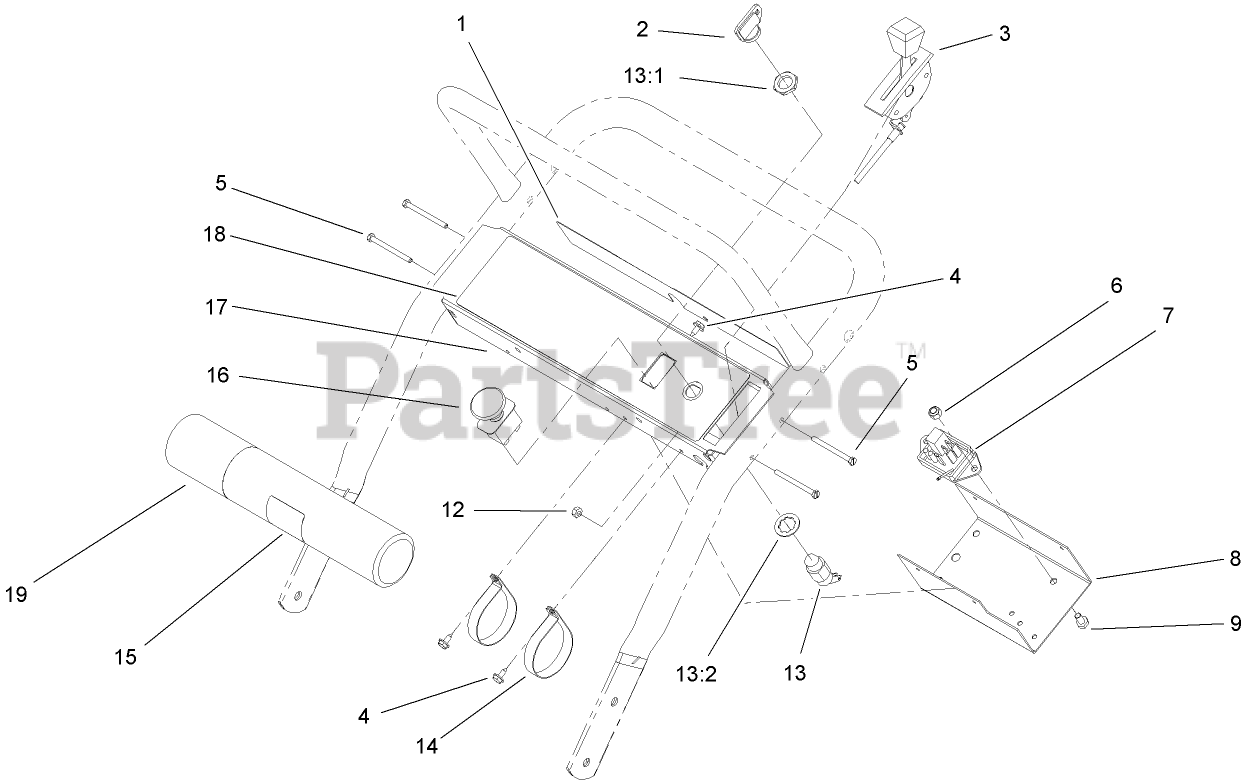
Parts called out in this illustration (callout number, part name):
1	DECAL-DANGER
2	KEY-IGNITION
3	CABLE-THROTTLE
4	SCREW-HWHTF
5	SCREW-SHH
6	NUT-LOCK, NI
7	MODULE-DELAY
8	PANEL-BOTTOM
9	SCREW-HH
12	NUT-LOCK, NI
13	SWITCH-ON / OFF
13:1	NUT-HH
13:2	WASHER-TOOTH, INTERNAL
14	CLAMP-R
15	TUBE-MANUAL
16	SWITCH-PTO
17	PANEL-CONTROL
18	DECAL-CONTROL PANEL
19	CAP-HOUSING
